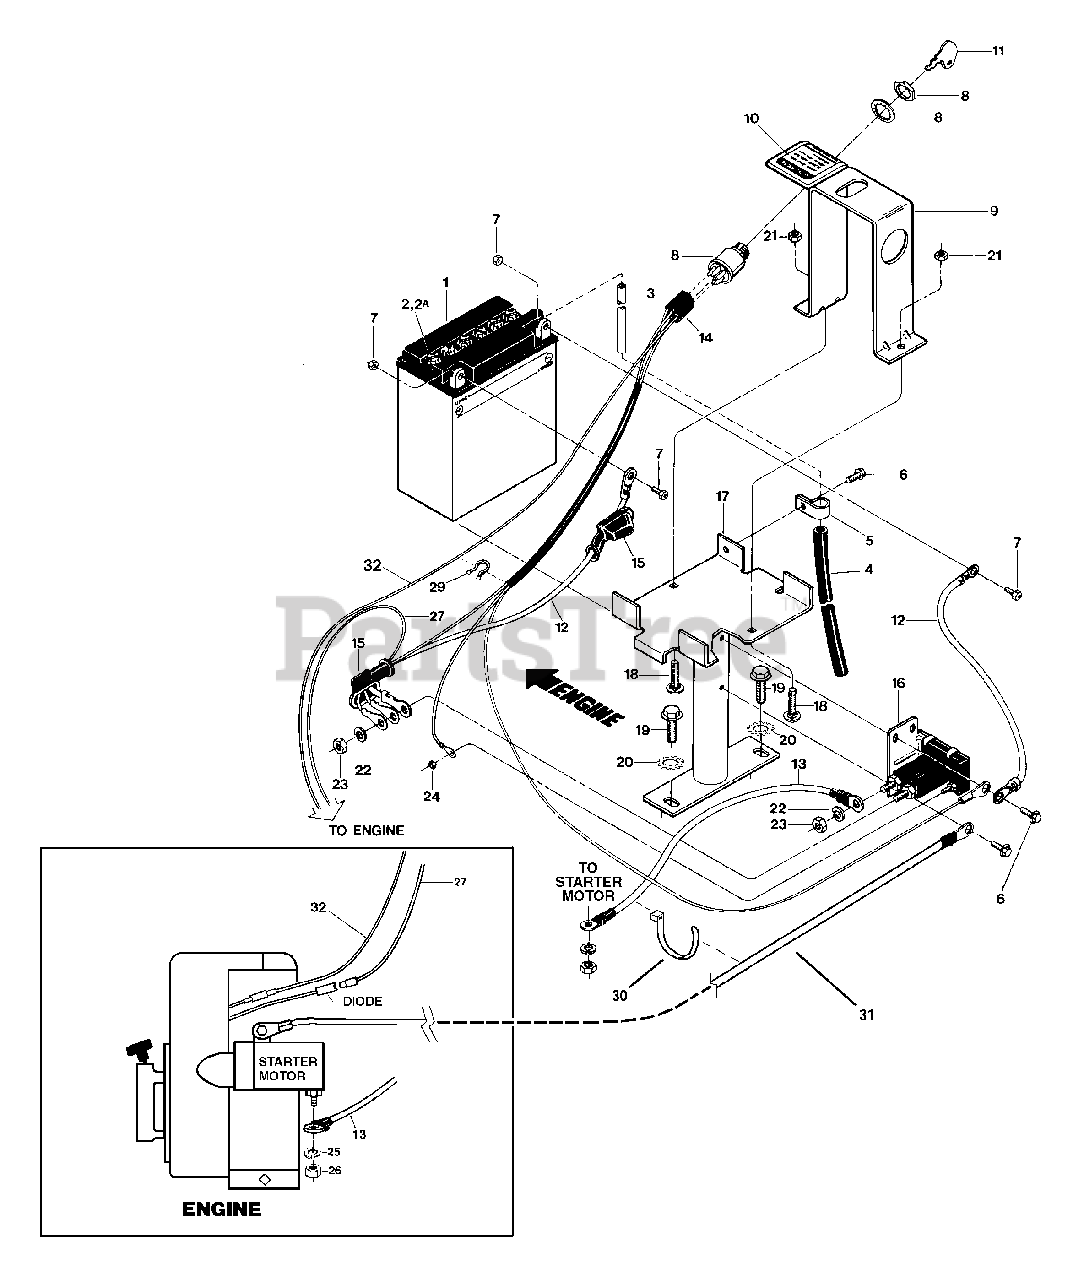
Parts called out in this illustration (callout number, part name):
1	Battery, 12 Volt, 9 Amp
2	Battery Cap (yellow)
2A	Battery Cap (white)
3	Vent Tube
4	Shield, Vent Tube (hard plastic)
5	Clamp
6	Hex Flange Screw, Self-Threading, 1/4-20 x 1/2
7	Battery Hardware Kit-
8	Ignition Switch
9	Battery Hold-Down Clamp/Switch Mounting Plate Assy.
10	Decal, Ignition Switch
11	Ignition Key (pair)
12	Battery Cable
13	Cable (solenoid to starter motor)
14	Wire Harness Assy.
15	Boot, Insulating
16	Solenoid
17	Battery Bracket
18	Round Hd. Screw, Square Neck, 1/4-20 x 1-1/4
19	Hex Flange Screw, 5/16-18 x 1
20	Lockwasher, External Tooth
21	Hex Locknut, 1/4-20
22	Lockwasher, 5/16
23	Hex Nut, 5/16-24
24	Hex Locknut, #10-32
25	Lockwasher, #10 (not available from factory)
26	Hex Nut, #10-24 (not available from factory)
27	Recharge Wire Assembly
29	Plastic Wire Tie
30	Plastic Wire Tie
31	Cable (ground wire to starter motor bracket)
32	Ground Wire Assy. (shut off)
